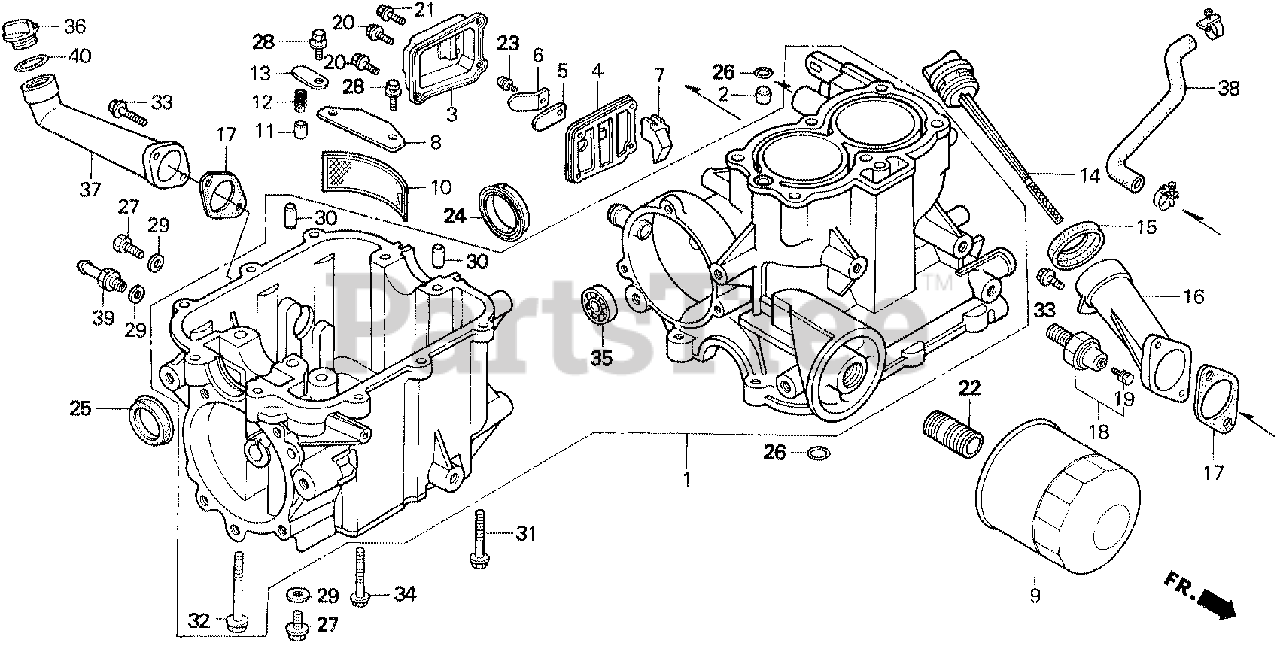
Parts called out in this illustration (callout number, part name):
1	CYLINDER ASSY.
2	ORIFICE, OIL CONTROL
3	COVER, BREATHER
4	PLATE, BREATHER
5	PLATE, VALVE
6	STOPPER, VALVE
7	GUARD, BREATHER
8	PLATE, OIL FILTER
9	FILTER, OIL
9	FILTER, OIL (DENSO)
9	FILTER, OIL (TOYO ROKI)
10	SCREEN, OIL FILTER
11	VALVE, CHECK
12	SPRING, VALVE
13	PLATE, VALVE
14	CAP, OIL FILLER
15	GASKET, OIL FILLER CAP
16	PIPE, OIL FILLER
17	GASKET, OIL PIPE
18	SWITCH, OIL PRESSURE
19	BOLT-WASHER (4X8)
20	BOLT, FLANGE (6X12) (CT200)
21	BOLT, FLANGE (6X14)
22	PIPE, OIL PASSAGE
23	SCREW-WASHER (5X8)
24	OIL SEAL (33X48X7)
25	OIL SEAL (30X44X7)
26	O-RING (10.8X2.4) (ARAI)
27	BOLT, DRAIN PLUG (12MM)
28	BOLT-WASHER (6X12)
29	WASHER, DRAIN PLUG (12MM)
30	PIN A, DOWEL (10X16)
31	BOLT, FLANGE (6X28)
32	BOLT, FLANGE (8X55)
33	BOLT, FLANGE (6X16)
34	BOLT, FLANGE (6X32)
35	BEARING, RADIAL BALL (6202)
